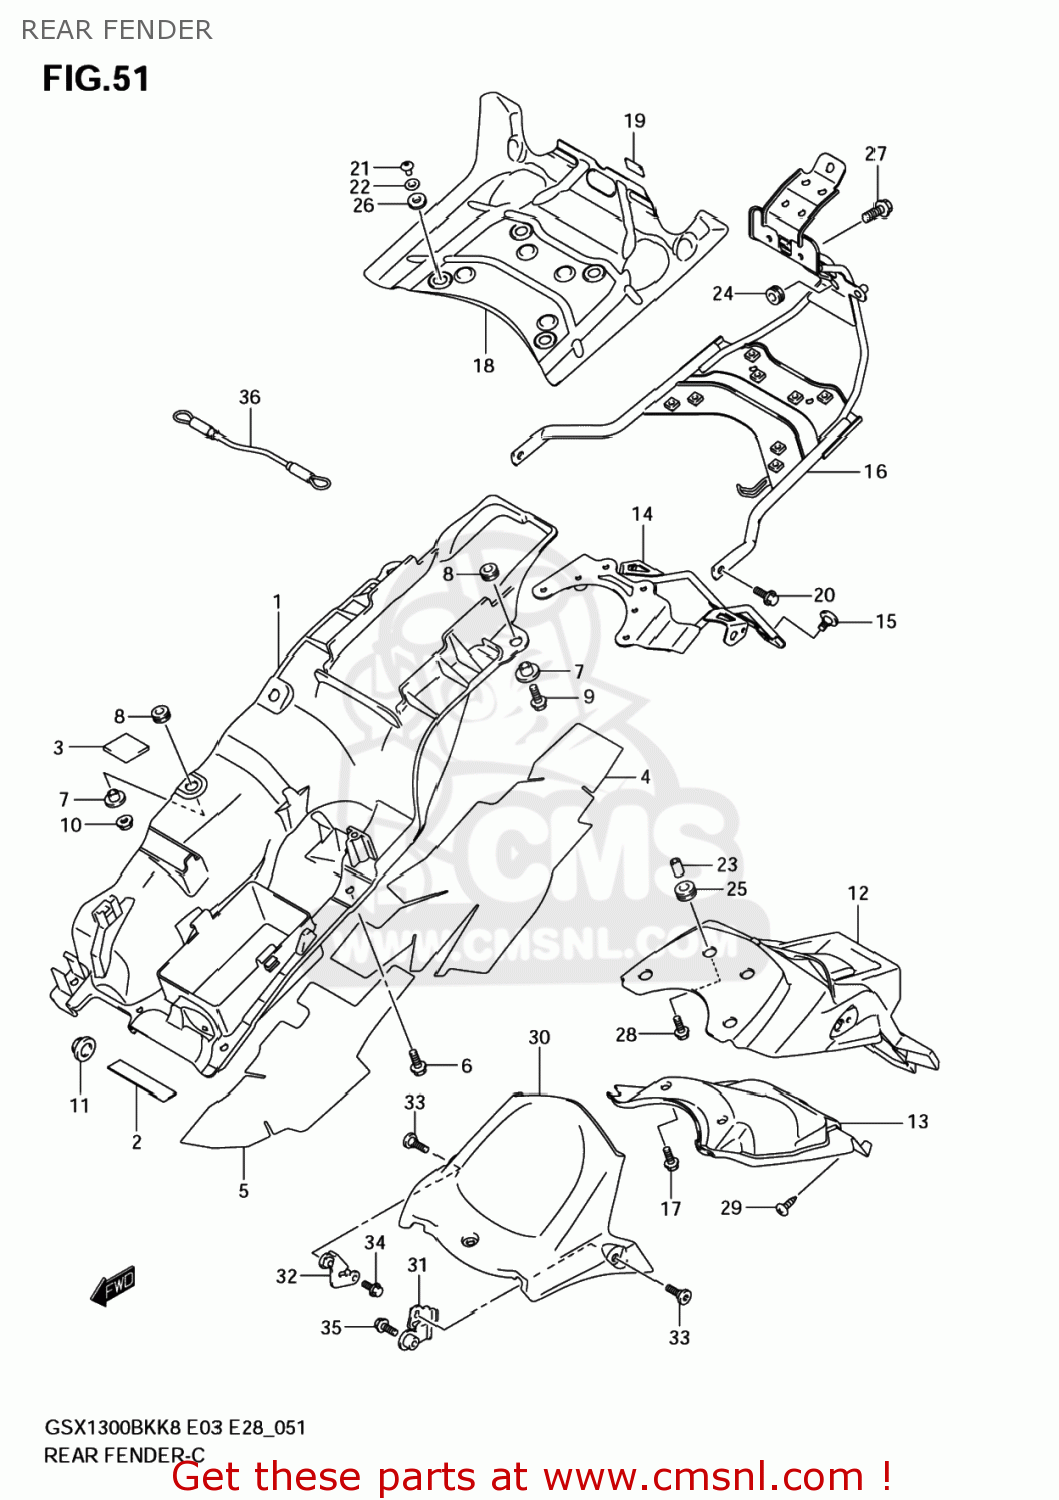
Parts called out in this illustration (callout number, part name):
1	FENDER,RR FR
2	PROTECTOR(20X90)X2
3	CUSHION
4	SHIELD,RR FENDER NO.1
5	SHIELD,RR FENDER NO.2
6	BOLT(6X16)
7	SPACER(6.5X10X11.6)
8	CUSHION
9	BOLT
10	NUT
11	CUSHION
12	FENDER,RR RR
13	COVER,RR FENDER RR
14	BRACKET COMP,R
15	SCREW(6X12)
16	BRACE,RR FENDER
17	BOLT
18	HEATSHIELD,RR FENDER
19	CUSHION,HEAT SHIELD RR
20	BOLT(8X16)
21	SCREW(6X12)
22	WASHER
23	SPACER(6X12X10)
24	CUSHION
25	CUSHION,RR FENDER RR
26	CUSHION
27	BOLT
28	BOLT(6X25)
29	SCREW
30	FENDER,REAR LO
31	BRACKET,RR FENDER LWR,L
32	BRACKET,RR FENDER LWR,R
33	SCREW(6X12)
34	BOLT
35	BOLT
36	CABLE,HELMET LOCK
